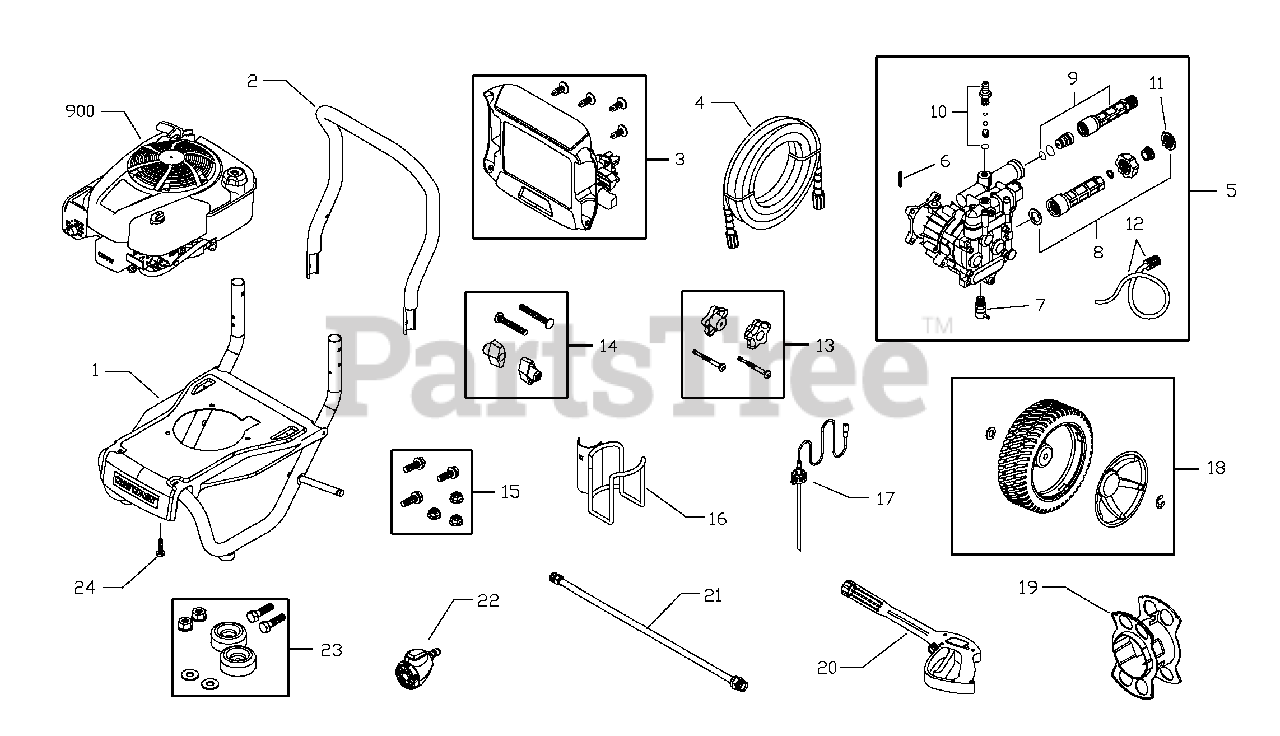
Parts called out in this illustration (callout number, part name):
1	BASE
4	HOSE
5	PUMP
7	VALVE, Thermal Relief
8	KIT, Water Inlet
9	KIT, Water Outlet
10	KIT, Chemical Injection
11	FILTER, Garden Hose
12	KIT, Chemical Hose
13	KIT, Hardware Handle
14	KIT, Hardware Handle
15	KIT, Hardware, Pump Mounting
20	GUN
21	EXTENSION, QC
22	NOZZLE, QC
23	KIT, Vibration Mount
900	*ENGINE
